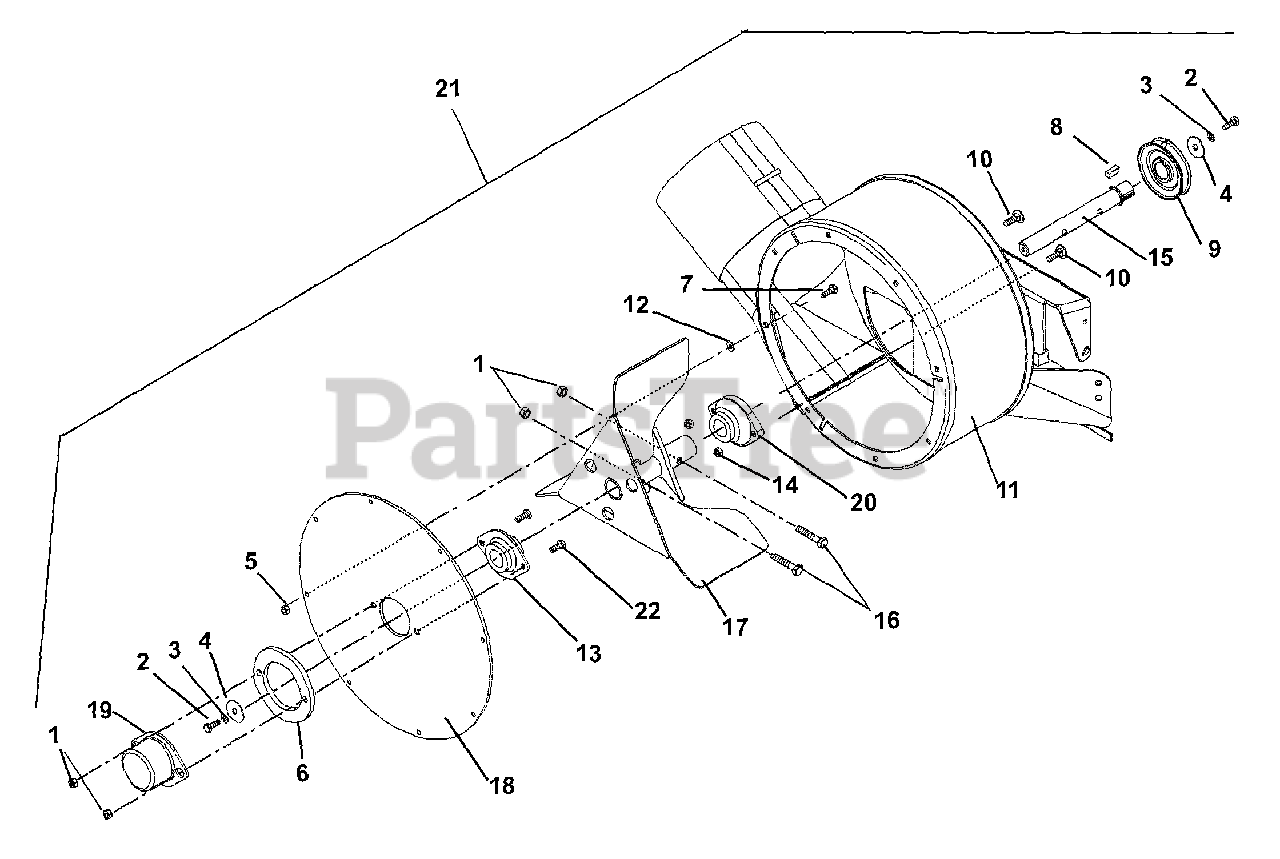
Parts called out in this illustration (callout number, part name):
1	Nut-Locking-Center .31-18
2	Bolt-Hex .25-20 x .75 Grade 5
3	Washer-Locking .25 x .062 Regular
4	Washer-Flat-Steel .265 x 1.370 x .179
5	Nut-Locking-Center .25-20
6	Plate, Retainer
7	Bolt-Round Head Square Neck .25-20 x .50
8	Key-Square .25 x .25 x 1.00
9	Pulley-V 3.50 x 1.004 w/key
10	Bolt-Round Head Square Neck .31-18 x 1.00
11	Weldment, Blower Housing
12	Nut, Push .25 x .50
13	Bearing-2 Bolt x 1.00 Shaft
14	Nut-Locking-Top-Flange .31-18
15	Shaft-Impeller
16	Bolt-Hex .31-18 x 1.75 Grade 5
17	Weldment, Bagger Impeller
18	Cover-Bearing Support
19	Cover-Bearing
20	Bearing, Flange w/Set Screw 1.00 ID
21	Assembly, Blower Housing
22	Bolt, Hex .31-18 x 1.0
